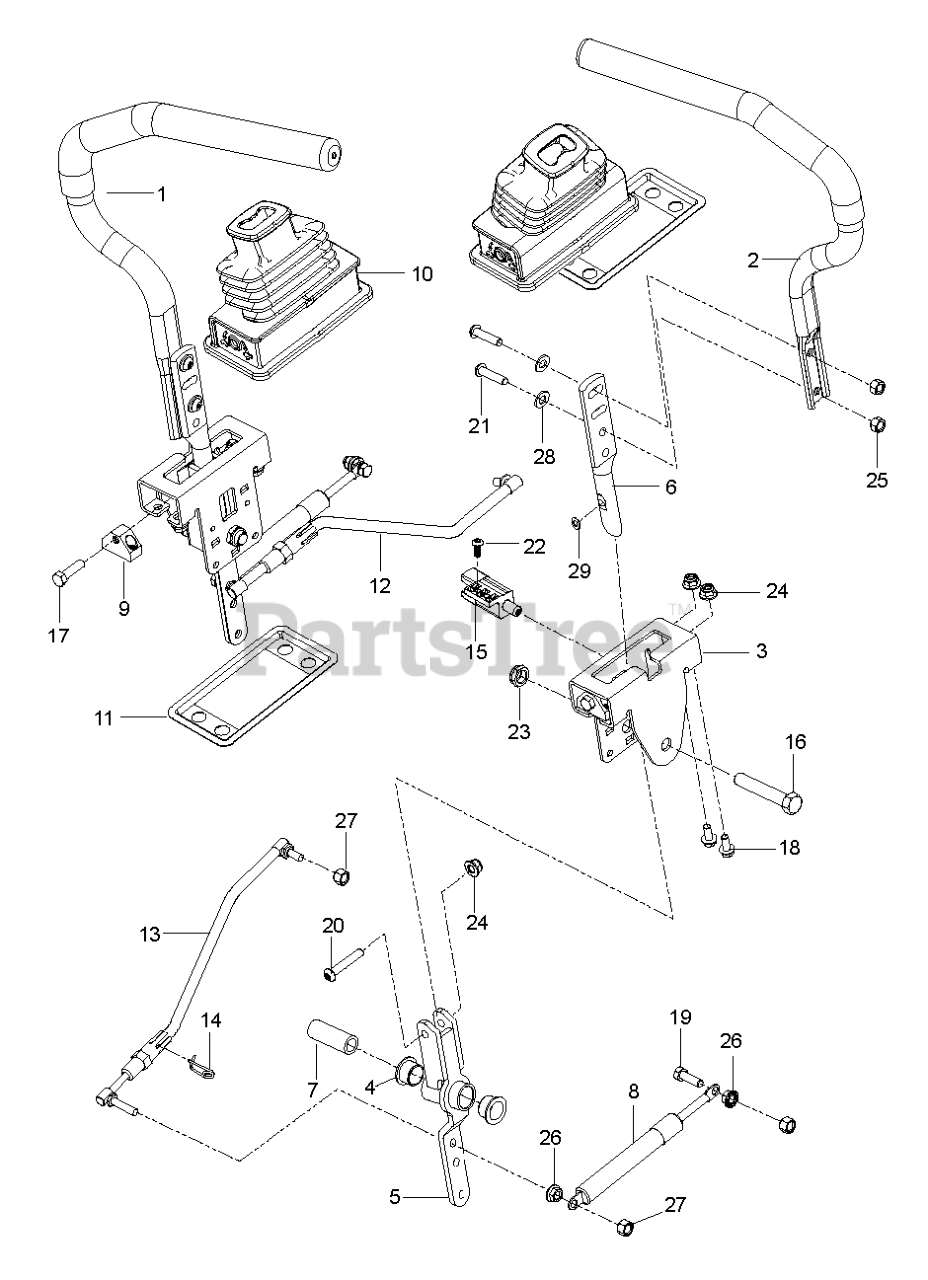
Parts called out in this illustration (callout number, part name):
1	TUBE.LEVER.CONTROL.ZTR.RT.428
2	TUBE.LEVER.CONTROL.ZTR.LT.428
3	BRACKET.CONTROLS.ZTR.X431
4	BEARING, FLANGE
5	LEVER CONTROL PIVOT
6	CONTROL.LEVER.HANDLE
7	SPACER.PIVOT.CONTROL
9	BLOCK TRACKING CONTROL ZTR
10	BOOT.STEERING.LEVER
11	CONTROL.BOOT.FLANGE.X431
12	ROD.ASM.RH.ADJUSTABLE
13	ROD.ASM.LH.ADJUSTABLE
14	RETAINER.CLIP.SPRING.S
15	SWITCH.INTLK.RZ.RFRSH.BUTTON
16	HCS 1/2-13 X 2-3/4 GD 5 ZD
17	SCREW.SHAKEPROOF.1.25.BLACK
18	HHFS 5/16-18 X 3/4
19	HCS 5/16C X 1
20	SCREW.CAP.SOCKET.6PT.5/16-18
21	BUTTONHEAD.5/16-18X1.125.BLACK
22	SCREW.BUTTONHD.10-24X1/2.(2 2)
23	NUT 1/2-13 HEX JM NYL
24	5/16-18 NYLOC FLANGE NUT
25	NYLOCK.NUT.5/16-18 BLACK
26	NUT 5/16C WHIZ
27	NUT.71038.31-18.HEX.NYLOCK
28	WASHER
29	WASHER.11/32ID.11/16OD.116THIC
